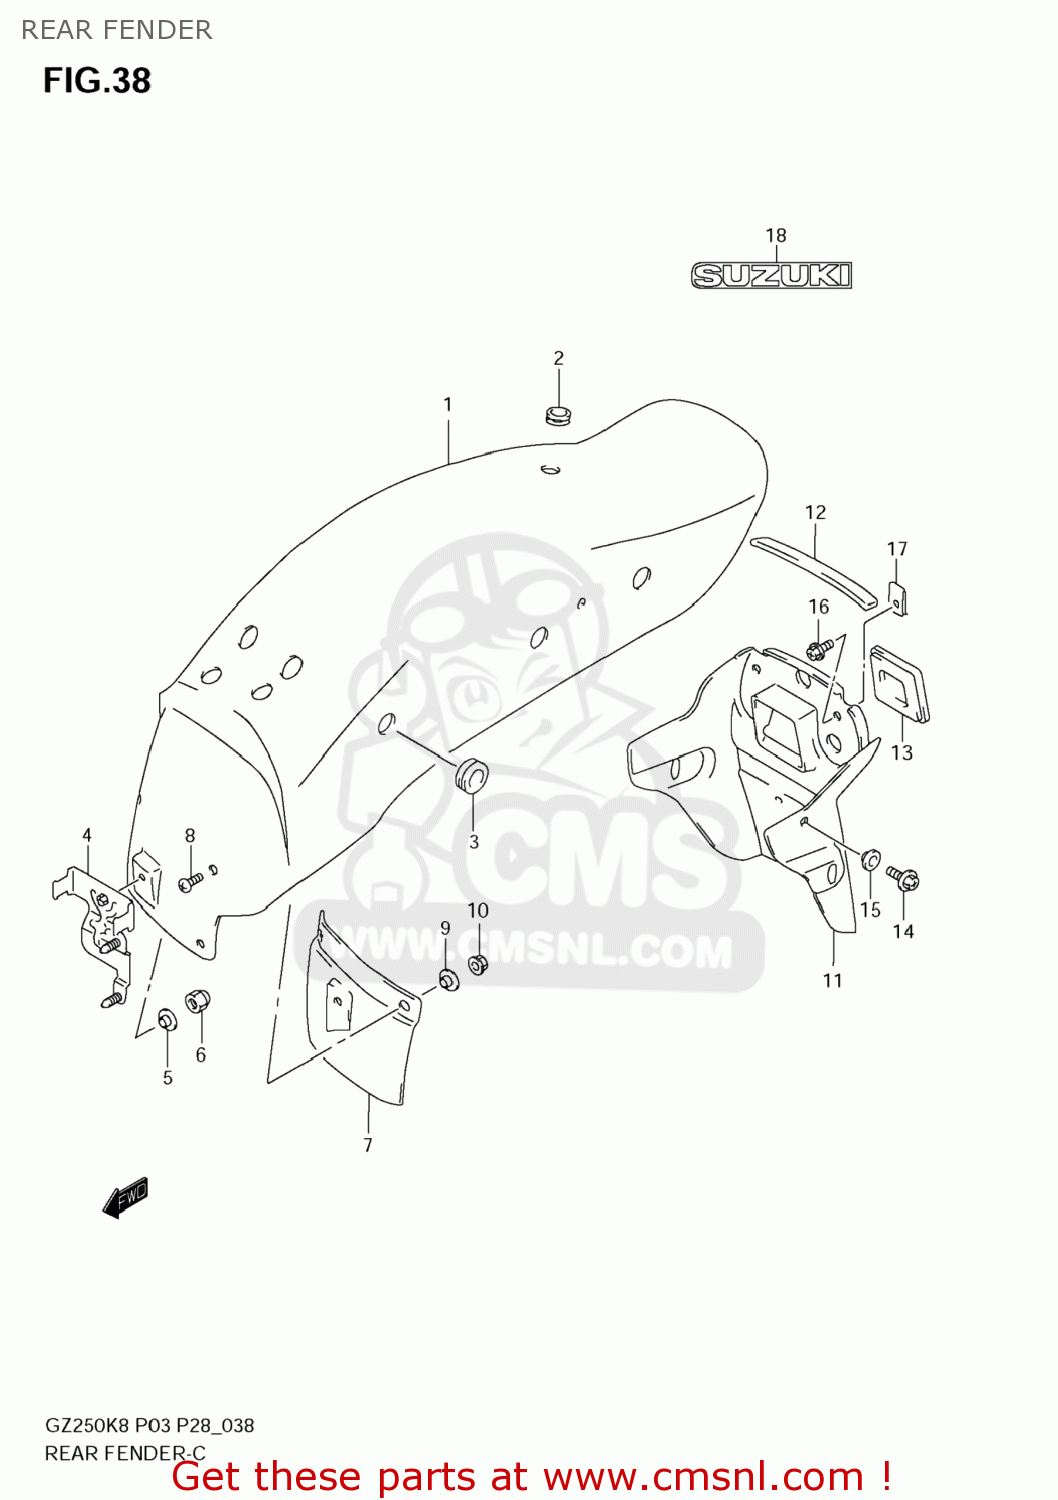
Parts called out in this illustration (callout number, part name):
1	FENDER,REAR
2	CUSHION
3	CUSHION,RR FENDER
4	BRACKET,RR FENDER
5	WASHER
6	NUT
8	SCREW
9	WASHER
10	NUT
11	EXTENSION, REAR FENDER
12	CUSHION,RR FENDER EXTENSION
13	CAP,RR FENDER EXTENSION
14	SCREW
15	WASHER
16	SCREW
17	PLATE,FRAME COVER
18	EMBLEM "SUZUKI" (GRAY)
